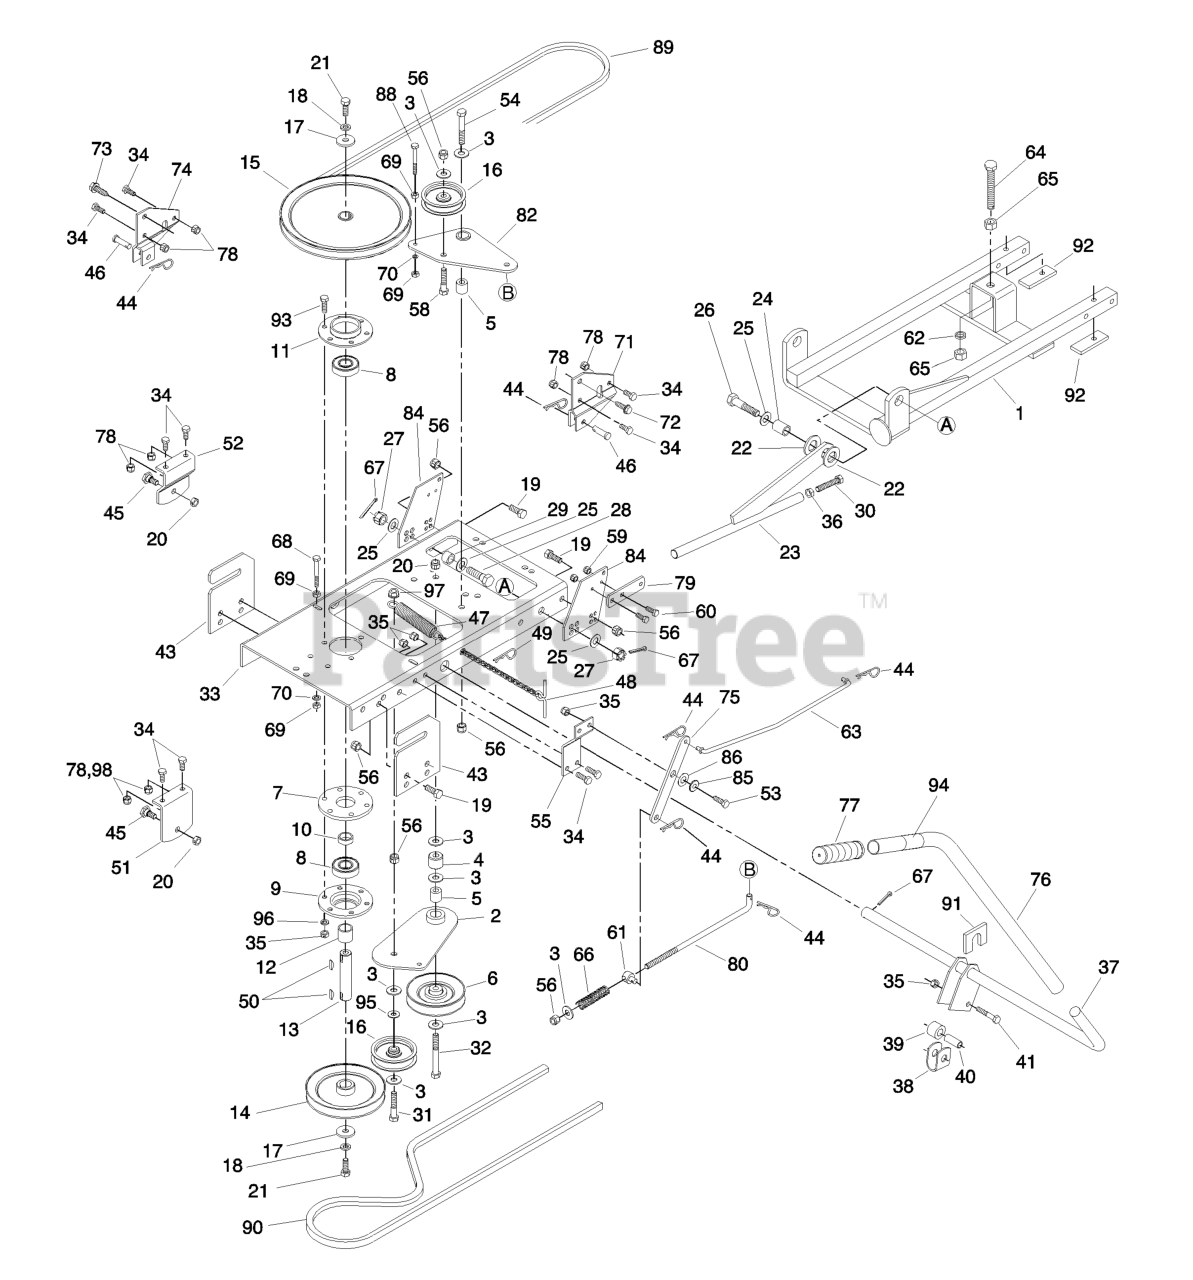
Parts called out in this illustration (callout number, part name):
1	Mounting Frame Assembly
2	Idler Bracket Assembly
3	Washer, 3/8" Flat
4	Spacer, .41 ID x 1.0 OD x .75" L
5	Bushing, .38 ID x .75 OD x .75" L
6	Pulley, V Idler 4" Dia.
7	Spacer, Spindle
8	Bearing, Ball
9	Housing, Bearing
11	Housing, Open Bearing
13	Shaft, .787 Dia. x 3.81 L
14	Pulley, 5-1/2" Dia.
15	Pulley, 9" Dia.
16	Pulley, 3-3/4" Dia.
17	Washer, Flat .406" ID x 1.25" OD
18	Lockwasher, 3/8"
19	Hex Bolt, 3/8-16 x 1"
20	Hex Lock Nut, 3/8-16
21	Hex Bolt, 3/8-24 x 1"
22	Washer, 13/16" x 1-1/2" x .134"
23	Lift Extension Assembly
24	Spacer, .53" ID x .75 OD" x 1.0" L
25	Washer, 17/32" x 1" x 16 Ga.
26	Hex Bolt, 1/2-20 x 2-1/4" Gr. 8
27	Castle Nut, 1/2-20
28	Hex Bolt, 1/2-20 x 1-3/4" Gr. 8
29	Spacer, .53" ID x .75" OD x .50" L
30	Hex Bolt, 3/8-16 x 2" (Full Thread)
31	Hex Bolt, 3/8-16 x 2-1/4"
32	Hex Bolt, 3/8-16 x 3-1/4"
33	Frame, Lift & Pulley
34	Hex Bolt, 5/16-18 x 3/4"
35	Hex Lock Nut, 5/16-18
36	Hex Nut, 3/8-16
37	Lift Bar Assembly
38	Bracket, Lift Stabilizer
39	Spacer, .53 ID x .75 OD x .75 L
40	Spacer, .37 ID x .50 OD x 1.125 L
41	Hex Bolt, 5/16-18 x 1-3/4"
43	Plate, Rear Mounting
44	Pin, Hairpin .09 x 1.58"
45	Shoulder Bolt, 3/8-16 x 5/8"
46	Clevis Pin, 3/8" x 1-1/4"
47	Spring, Extension .75" OD
48	Pull Chain
49	Pin, Haircotter (1/8")
50	Key, (Hi-Pro)
51	Bracket, Rear Hanger (RH)
52	Bracket, Rear Hanger (LH)
53	CAPSCREW, Hex Head, 5/16-18 x 1
54	Hex Bolt, 3/8-16 x 1-1/2"
55	Bracket, Pivot
56	Hex Lock Nut, 3/8-16 (Nylock)
58	Hex Bolt, 3/8-16 x 1-3/4"
59	Hex Lock Nut, 1/4-20 (Nylock)
60	Hex Bolt, 1/4-20 x 1"
61	Anchor, Clutch Rod
62	Lockwasher, 1/2"
63	Rod, Engagement
64	Hex Bolt, 1/2-13 x 3-1/2" Full Thd.
65	Hex Nut, 1/2-13
66	Spring, Coil
67	Pin, Cotter 1/8 x 1-1/4"
68	Hex Bolt, 1/4-20 x 2-3/4"
69	Hex Nut, 1/4-20
70	Lockwasher, 1/4"
71	Front Hanger Bracket (LH)
72	Screw, 5/16-18 x 1" Self Tap
73	Screw, 3/8-16 x 1-1/4" Thd. Form.
74	Front Hanger Bracket (RH)
75	Bell Crank Bracket
76	Handle, Lift
78	Hex Lock Nut, 5/16-18 (Nylok)
79	Bracket, Electric Clutch
80	Rod, Lower Clutch
82	Idler Arm Assembly
84	Plate, Front Mounting
85	Step Bushing
86	Washer, 1/2" x 1" OD x .020"
88	Hex Bolt, 1/4-20 x 1-1/2"
89	Belt, Upper
90	Belt, Lower
91	Lift Bar Bracket
92	Shim Strap
93	Hex Bolt, 5/16-18 x 1-1/4"
94	Label, Handle
95	Spacer, Bushing
96	Lockwasher, 5/16"
97	Hex Lock Nut, 3/8-16 (Washer Face)
